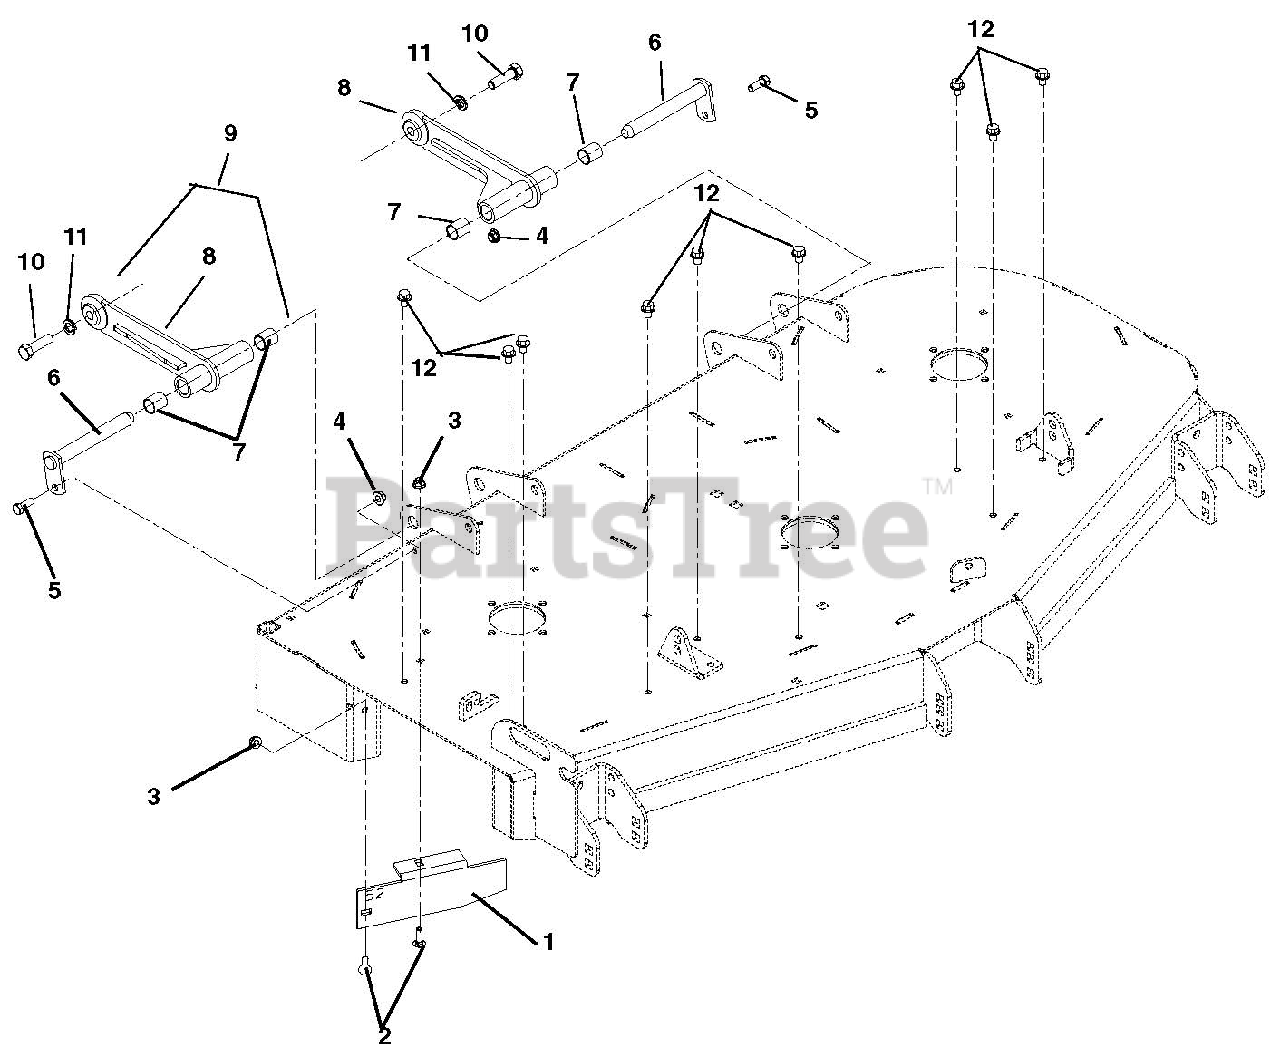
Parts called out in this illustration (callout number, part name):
1	Baffle, 60" Discharge
1	52" Discharge Baffle
1	44" - 48" Rear Discharge Baffle
2	Bolt, Round Head Square Neck .31-18 x 1.00 Grade 5
3	Nut, .31-18 Nyloc Flange
4	Nut, .38-16 Nyloc Flange
5	Bolt, Hex .38-16 x 1.00 Grade 5
6	Weldment, Mower Mounting Pin
7	Bearing, .75 x .875 x 1.00
8	Deck Pusher Arm Weldment
9	Assembly, Mower Mount Arm
10	Bolt, Hex .50-13 x 1.75 Grade 5
11	Washer, Locking .50 x .125 Regular
12	Screw, Tapping .38-16 x .50 Hex Washer Head
